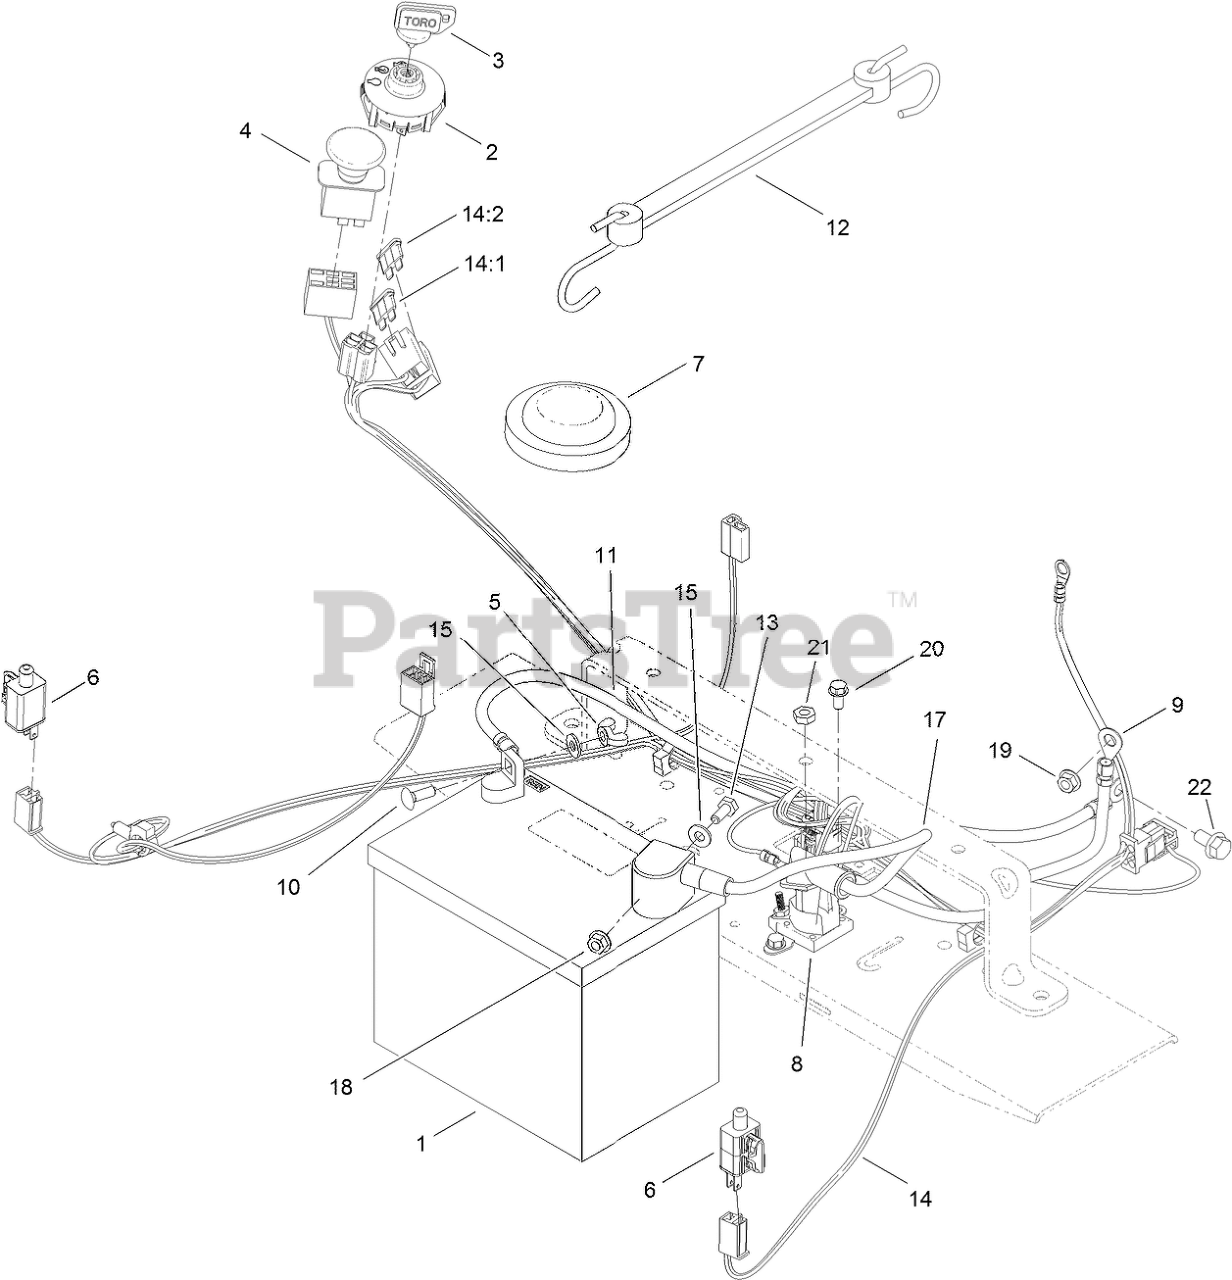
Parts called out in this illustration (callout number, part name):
1	BATTERY
2	SWITCH-IGNITION
3	KEY-IGNITION
4	SWITCH-PTO
5	NUT-WING
6	SWITCH
7	SWITCH-SEAT
8	SOLENOID
9	CABLE-BATTERY, POSITIVE
10	BOLT-CARR
11	CABLE-BATTERY, BLACK
12	HOLDDOWN-BATTERY
13	SCREW-HH
14	HARNESS-WIRE
14:1	FUSE-BLADE, 30 AMP
14:2	FUSE-BLADE, 25 AMP
15	WASHER-FLAT
17	CABLE-BATTERY, RED
18	NUT-HF
19	NUT-HF
20	SCREW-HWH
21	NUT-JAM
22	SCREW-HHF
